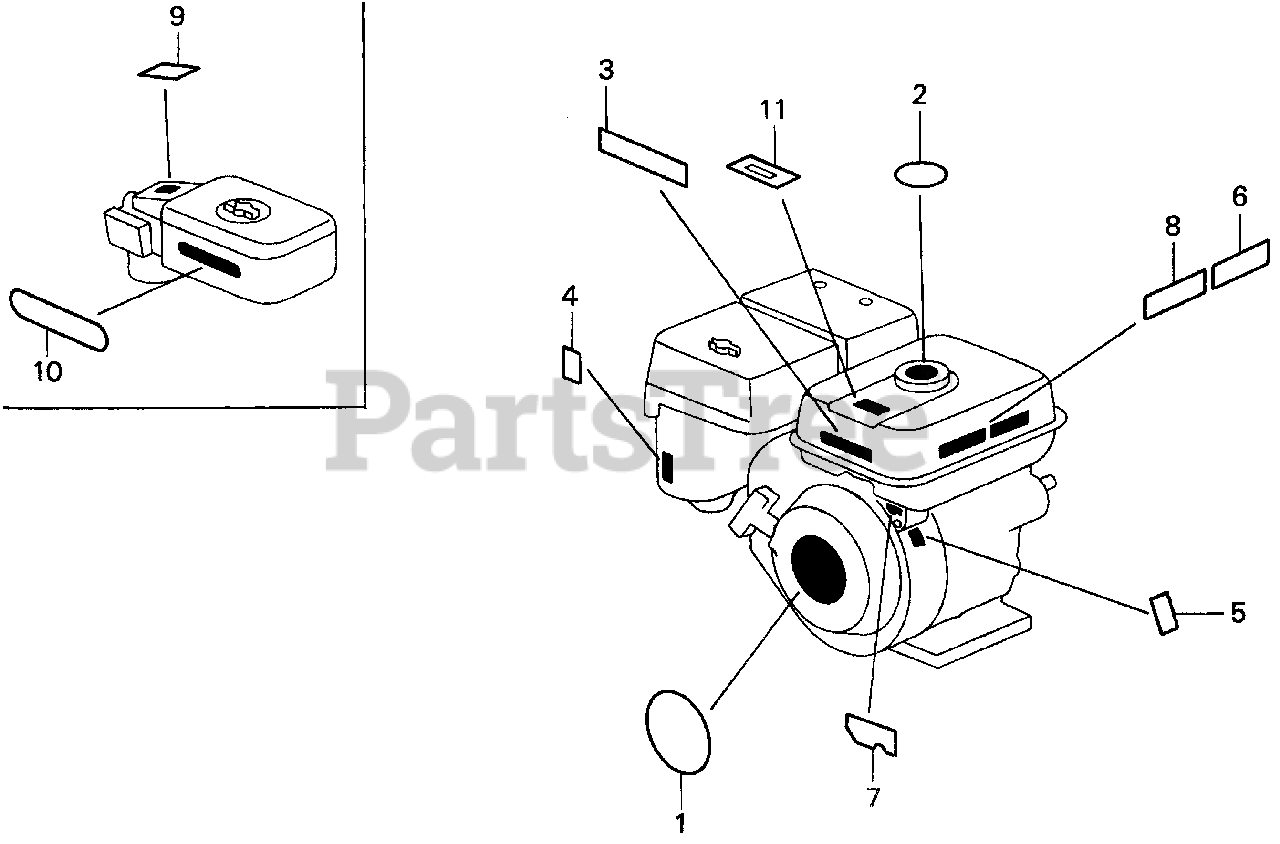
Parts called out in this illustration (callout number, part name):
1	EMBLEM (INTERNAL)
2	MARK, CAUTION (EXTERNAL)
3	LABEL, CAUTION
4	MARK, CHOKE (EXTERNAL)
5	LABEL, SPECIFICATION (EXTERNAL)
6	MARK, OIL ALERT (GERMAN)
6	MARK, OIL ALERT (FRENCH)
7	MARK, OIL ALERT (EXTERNAL)
8	MARK, OIL ALERT (E)
